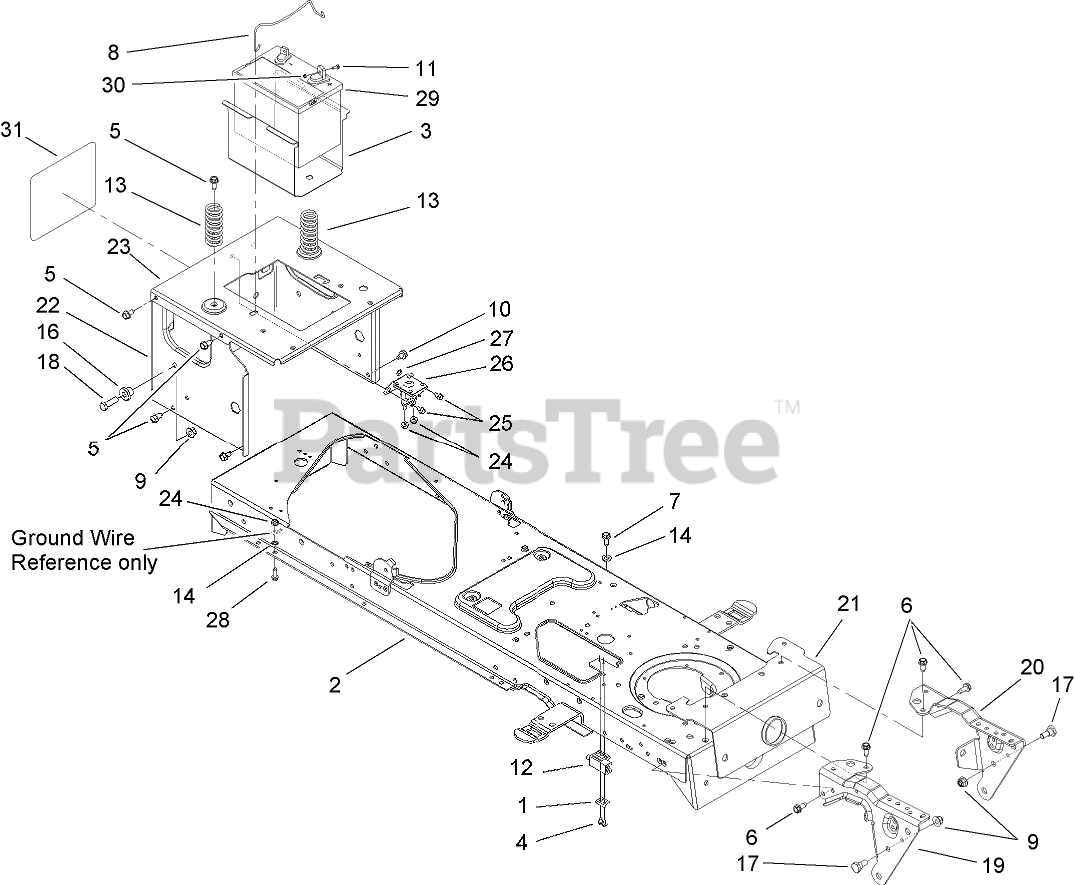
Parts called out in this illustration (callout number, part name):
1	PLATE-SWITCH
2	LOWER FRAME ASM
3	TRAY-BATTERY
4	SCREW-TAP
5	SCREW-HH, TAP
6	SCREW-HWH
7	SCREW-HWH
8	ROD-HOLDDOWN, BATTERY
9	NUT-LOCK, FLANGE
10	SCREW-TAP
11	BOLT-CARRIAGE
12	SWITCH-INTERLOCK
13	SPRING-COMPRESSION
14	WASHER-LOCK, EXTERNAL
16	SPACER-SHOULDER
17	BOLT-SHOULDER
18	SCREW-HH
19	BRACKET-PIVOT, SUPPORT
20	BRACKET-PIVOT, SUPPORT
21	BRACKET-PIVOT, BAR
22	FRAME-UPPER
23	BRACKET-FRAME, SEAT
24	NUT-LOCK, FLANGE
25	SCREW-HWHTF
26	SOLENOID-12V, 2 Post 1 Tab
27	WASHER-LOCK, EXTERNAL
28	SCREW-TAP
29	BATTERY-245, CCA (DRY FLAT TOP)
30	NUT-SEMS
31	DECAL-TORO
